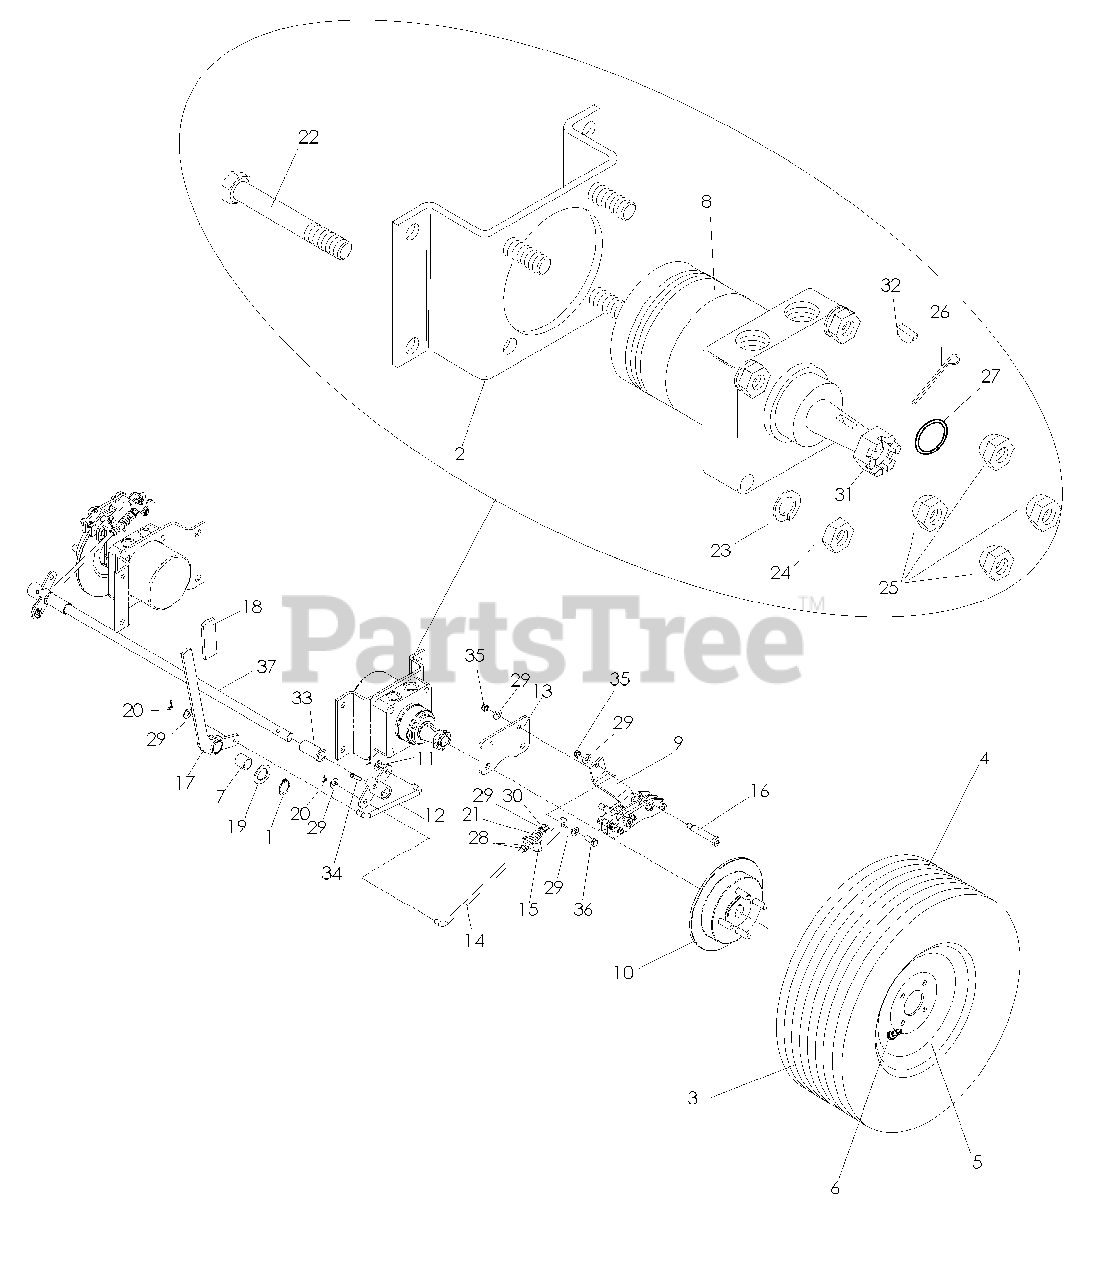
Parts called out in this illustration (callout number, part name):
1	RETAINING RING, 7/8"
2	MOTOR STANDOFF - PAINTED
3	TIRE ASSY 24-12
3	TIRE WHEEL ASM 23 X 9.5-12
4	TIRE.TURF.MASTER.24X12-12
5	RIM 2.5" NEG OFFSET 8.5" WIDE
6	VALVE STEM TR-412
7	BUSHING
8	TL15 WHEEL MOTOR
9	CALIPER ASSEMBLY
11	BELLCRANK, BRAKE
12	LINKAGE, BRAKE
13	PLATE, BRAKE
14	LINKAGE, REAR BRAKE
15	BRACKET, L
16	SB 3/8-16 X 2-1-1/2 SKT HDD ZD
17	LEVER, BRAKE WELDMENT
18	GRIP BRAKE HANDLE
19	BSHG .875 X 1.375 X .074 ZD
20	COTTER PIN 3/32 X 3/4
22	HCS 1/2C X 2 3/4
23	WASHER 1/2" SPLIT LOCK
24	NUT HEX 1/2
25	LUG NUT 1/2F
26	PIN COTTER 4MM X 45MM
27	MACHINE BUSHING
28	NUT 3/8-24 JAM
29	WASHER 3/8 SAE FLAT
30	NUT 3/8F CENTERLOCK
31	CASTLE-NUT
32	WOODRUFF KEY
33	BUSHING, POLYMER 3/4X2
34	5/16 DIA ROLL PIN
35	NUT HEX 3/8-16 NYLON, THIN
36	HCS 3/8C X 1
